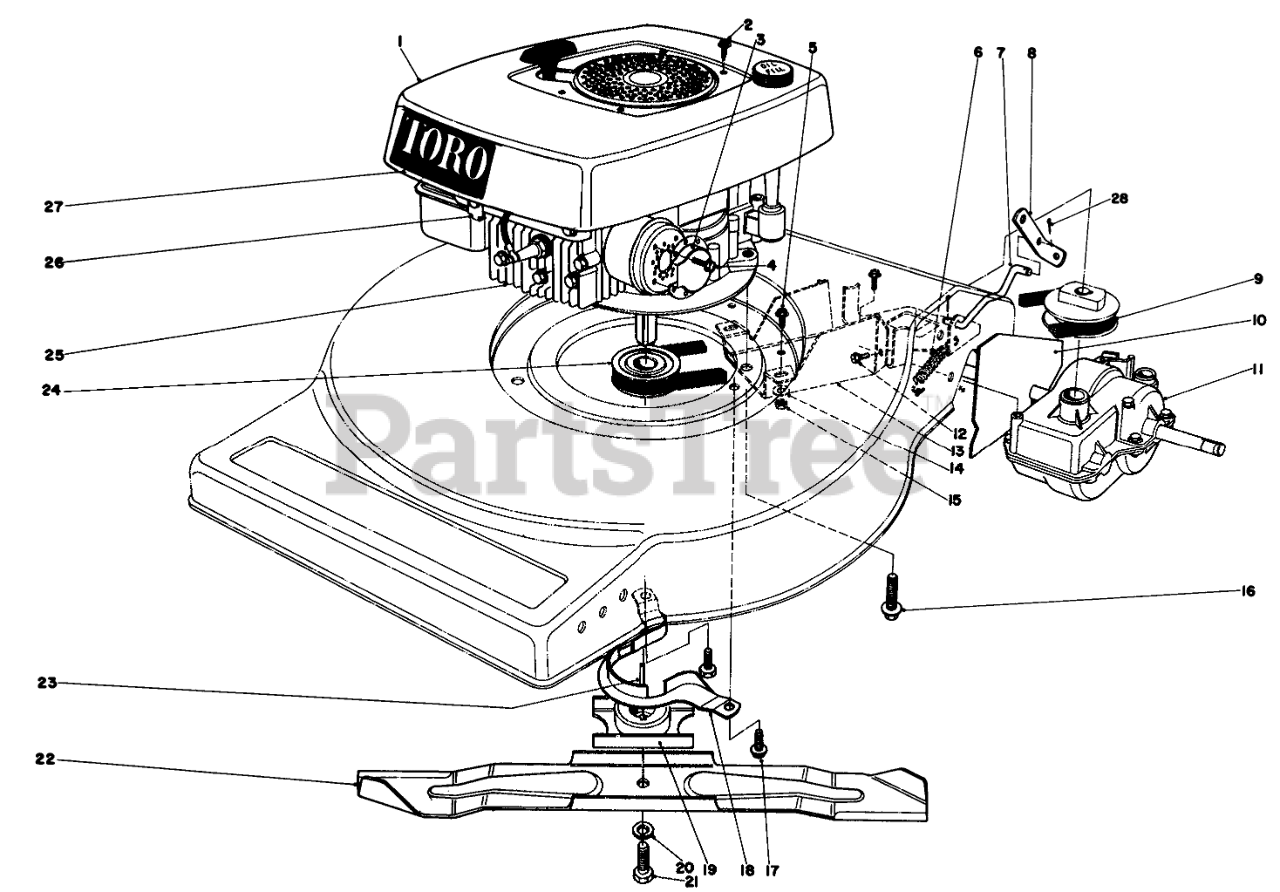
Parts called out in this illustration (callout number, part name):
1	SHROUD
2	8X1/2 SELF TAP SCREW
3	Deflector
4	SCREW W/ENGINE
5	SCREW-HWH
6	IDLER SPRING
7	Link Clutch
8	Bracket Clutch Pivot
9	V-BELT
10	GRASS SHIELD
11	Gear Case Assembly Complete
12	SCREW-HWHTF
13	COVER-BELT
14	WASHER-FLAT
15	Nut
16	PAD-BUMPER
17	Screw
18	BELT GUIDE
19	Blade Retailer
20	WASHER-LOCK
21	SPECIAL SCREW
22	Blade
23	KEY-SQUARE
24	DRIVER PULLEY
25	Engine
26	Bracket Control
27	Decal Shroud
28	PIN-COTTER
